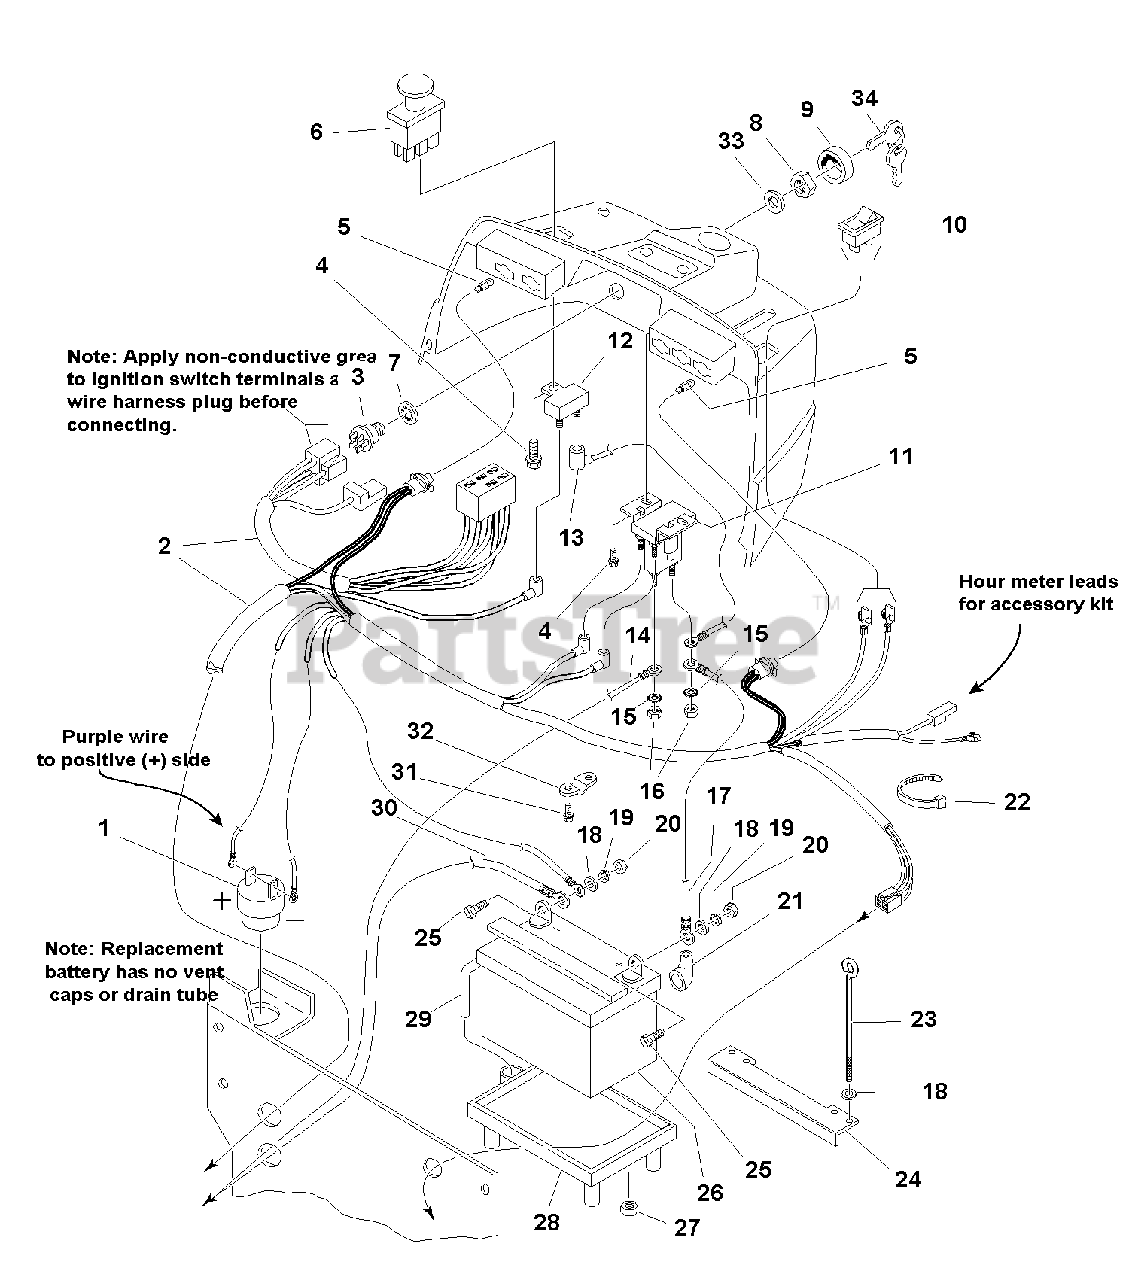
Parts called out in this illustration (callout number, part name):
1	BUZZER, Pulse, (Grass Bag Full)
2	HARNESS, Wiring
3	SWITCH ASSEMBLY, Ignition 5/8-32 6 Terminal (Includes Ref. Nos. 7, 8, 9, 33 & 34)
4	CAPSCREW, Hex Washer Head, 1/4 x 1/2
5	LAMP, Indicator
6	SWITCH, PTO Push/Pull w/Symbols
7	LOCKWASHER, Internal Tooth, 5/8
8	NUT, Hex Flange 5/8-32
9	COVER, Ignition Switch
10	SWITCH, Rocker, Headlight
11	SOLENOID, 4 Pole 12 Volt DC
12	BREAKER, Circuit 12 Volt 20 amps w/Tab
13	WIRE, 12GA, Red
14	CABLE, # 6 x 25 Long (2) Ring Terminals
15	LOCKWASHER, External Tooth, 5/16
16	NUT, Hex, 5/16-24 NF
17	CABLE, # 6 x 8 Long, (2) Ring Terminals
18	WASHER, 1/4
19	LOCKWASHER, 1/4
20	NUT, Hex, 1/4-20
21	BOOT, Insulator, Battery Terminal
22	TIE, Self Locking, 7-5/16" Long
23	ROD, Battery Hold Down
24	BRACKET, Battery Hold Down
25	CAPSCREW, Hex Head, 1/4-20 x 3/4
26	BATTERY, 12 Volt 6 Cell 340 amps
27	NUT, Plastic Expanding
28	TRAY, Battery
29	HOSE, Drain
30	CABLE, # 6 x 26 Long 1/4 & 3/8 Ring Terminals
31	CAPSCREW, Hex Washer Head, 3/8-16 x 1/2
33	WASHER, 5/8
34	KEY, Ignition (Set of 2)
